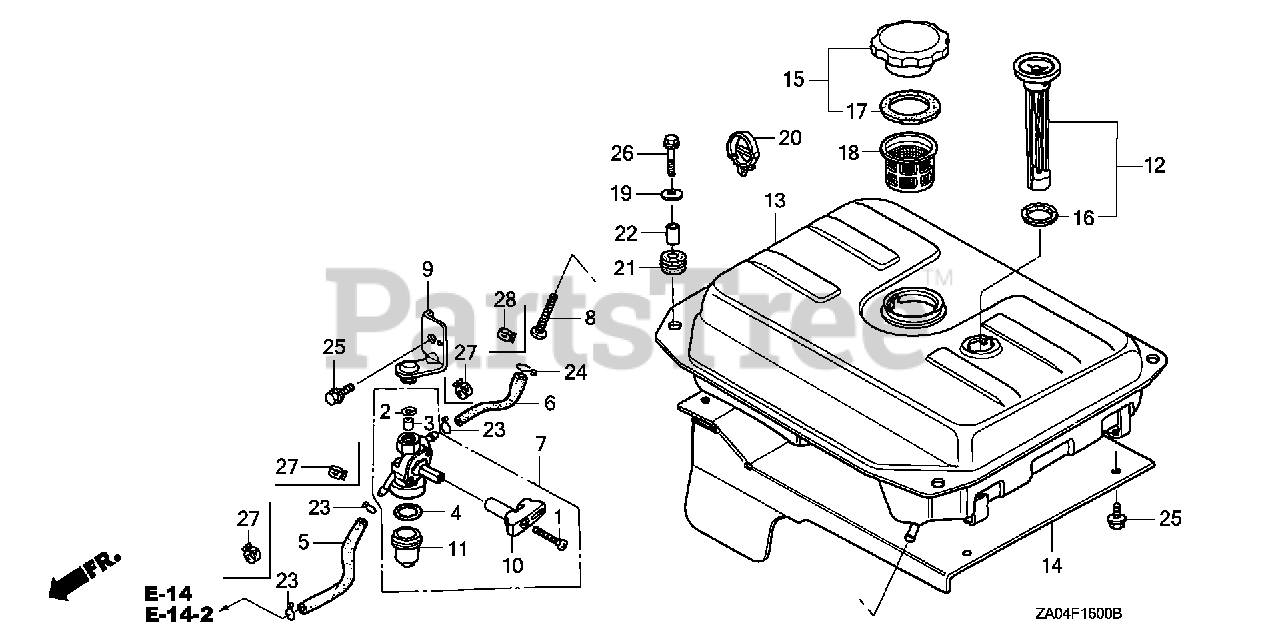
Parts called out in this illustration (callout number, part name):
1	SCREW, OVAL (4X32)
4	GASKET, FUEL STRAINER CUP
5	TUBE, CARBURETOR FUEL
5	TUBE, CARBURETOR FUEL (FKM)
6	TUBE, FUEL TANK
6	TUBE, FUEL TANK (FKM)
7	PETCOCK ASSY.
8	FILTER, FUEL
9	STAY, PETCOCK
10	LEVER, PETCOCK
11	CUP, FUEL STRAINER
12	METER, FUEL
13	TANK, FUEL *R280* (POWER RED)
14	PROTECTOR, FUEL TANK HEAT
15	CAP, FUEL FILLER
16	GASKET C, FUEL METER
17	GASKET, FUEL FILLER CAP
18	FILTER, FUEL
19	WASHER, TANK CUSHION
20	CLIP, WIRE HARNESS
21	CUSHION, TANK RUBBER
22	COLLAR, TANK CUSHION
23	CLIP, TUBE (B8)
24	CLIP, TUBE (B10)
25	BOLT, FLANGE (6X12) Use up to Engine SN 1543277.
26	BOLT, FLANGE (6X22)
27	CLIP, TUBE (D8)
28	CLIP, TUBE (10.5MM)
